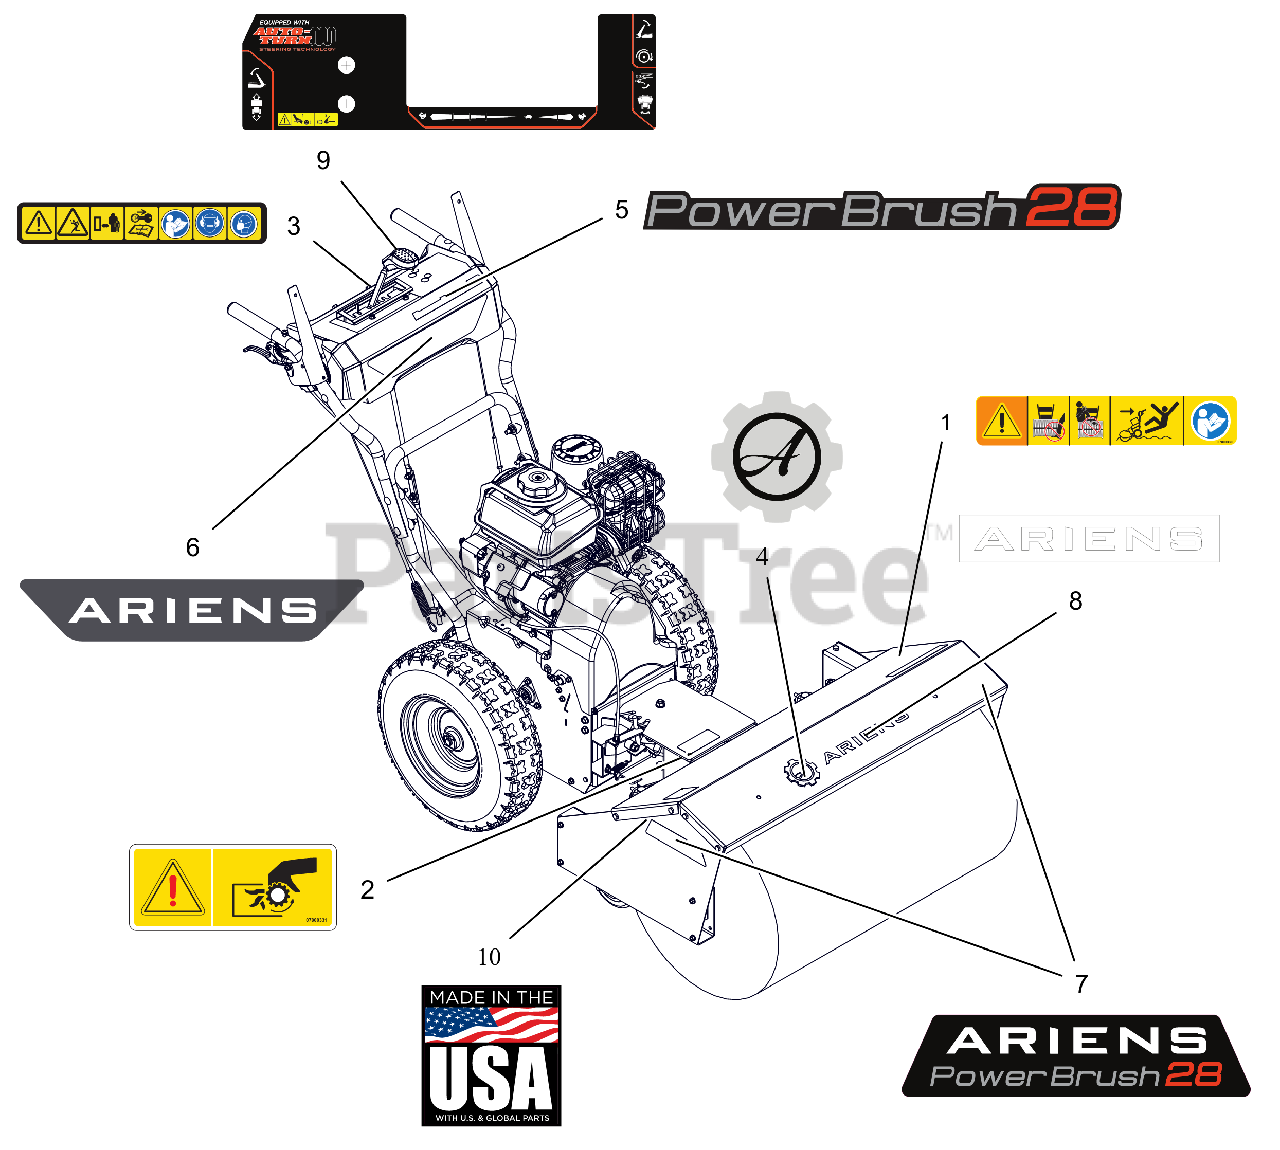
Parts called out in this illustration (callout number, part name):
1	DECAL, DANGER -POWER BRUSH-CE
2	DECAL, PTO WARNING
3	DECAL, SAFETY, DASH, BRUSH
4	DECAL, ARIENS-GEAR BADGE -THK
5	DECAL, DASH - PB 28
6	DECAL, DASH BRAND - ARIENS PB
7	DECAL - ARIENS PB 28
8	DECAL - ARIENS 9.625"
9	DECAL, CONTROL-SMALL BRUSH
10	DECAL, MADE IN USA
